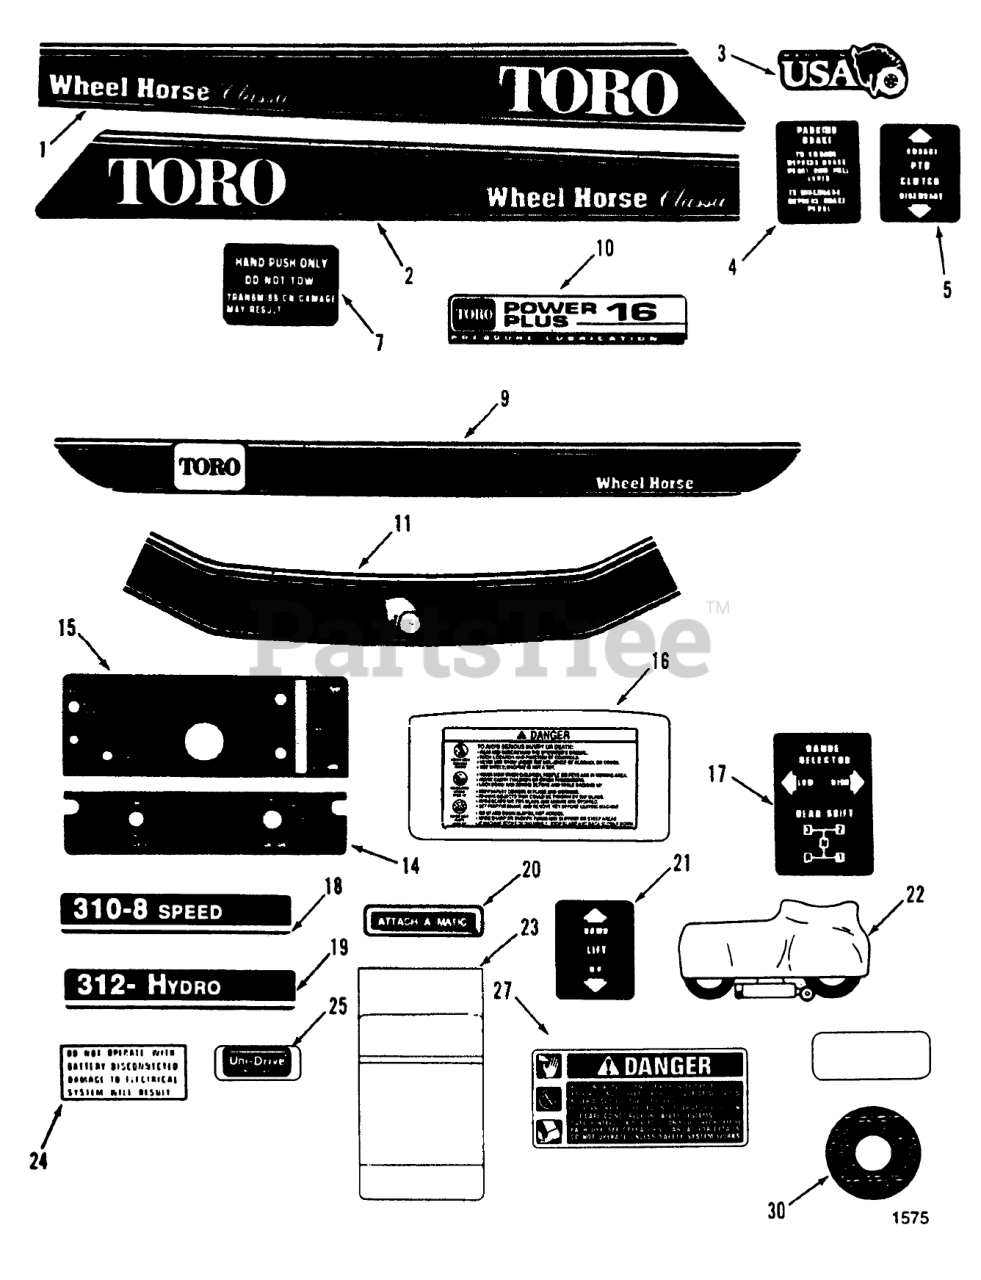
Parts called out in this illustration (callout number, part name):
1	DECAL-HOOD CLASSIC
2	DECAL-HOOD CLASSIC
3	Decal-Made In USA
4	DECAL-PARKING, BRAKE
5	DECAL PTO CLUTCH
7	DECAL-DO NOT TOW
9	DECAL-FENDER
10	DECAL-PWR PLUS 16 PL
11	DECAL-FRONT HOOD
14	Decal-Switch Plate
15	DECAL-LOWER DASH
16	Decal-Danger
17	DECAL-SHIFT PATTERN
18	Decal-310-8 Speed
19	DECAL-312 HYDRO
20	Decal-Attac-O-Matic
21	DECAL-LIFT
22	Vinyl Tractor Cover
23	MAINTENANCE-DECAL
24	DECAL ELECT SYSTEM
25	Decal-Unidrive
27	DECAL-DANGER
30	Decal-Air Cleaner
31	DECAL-COLD START
